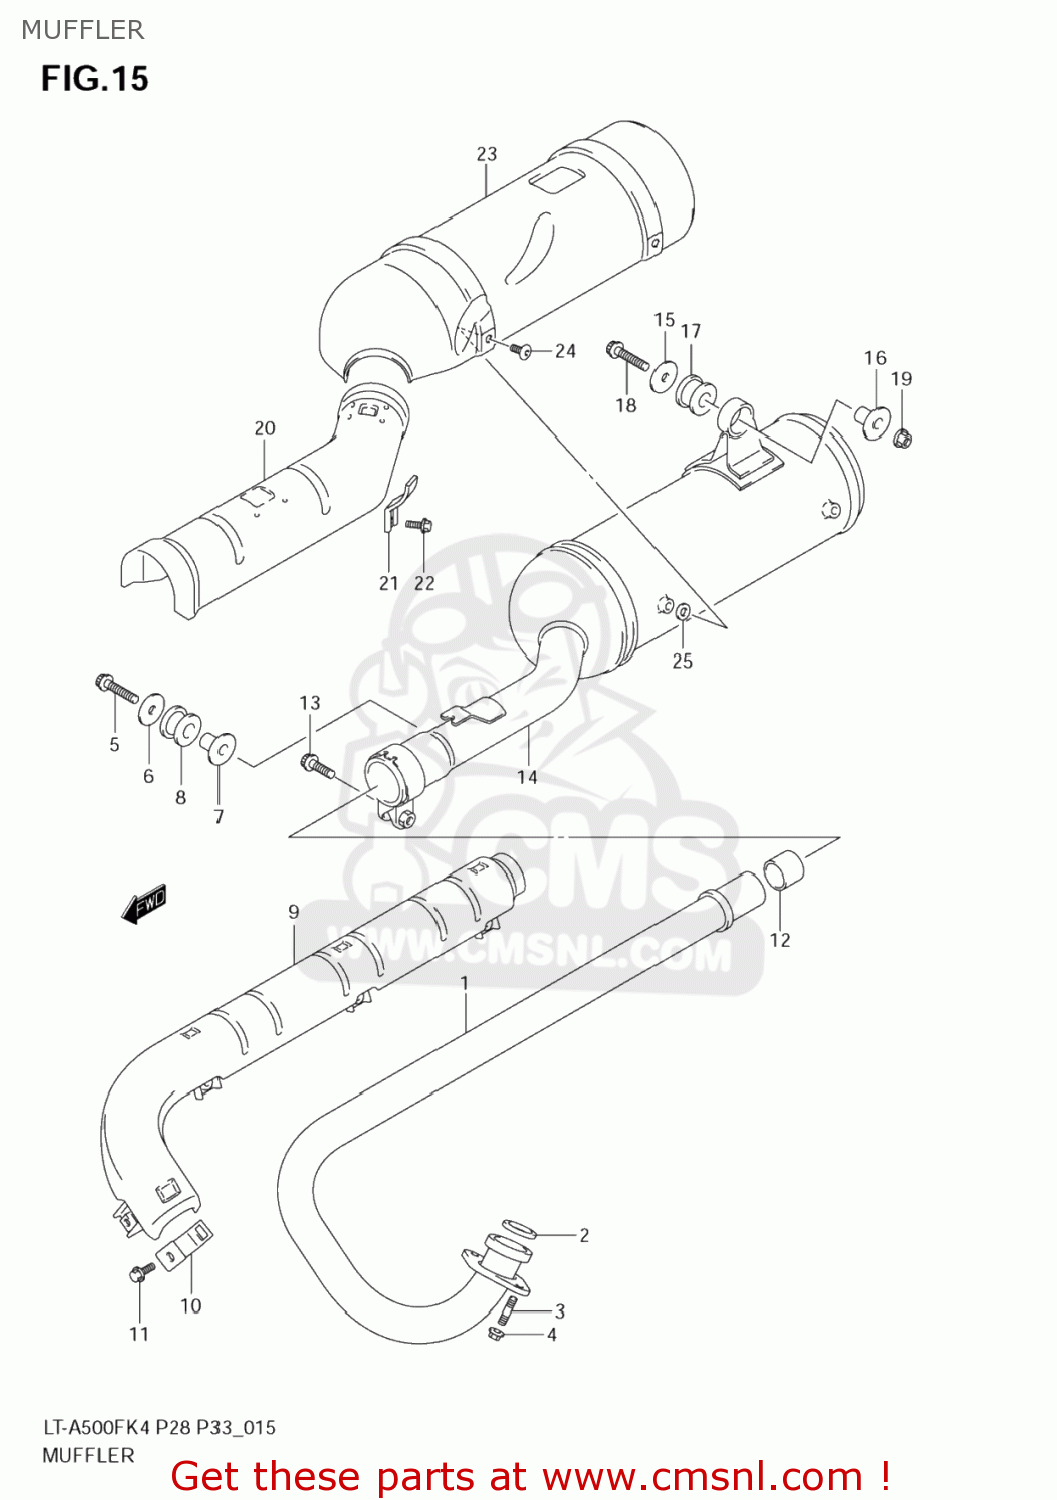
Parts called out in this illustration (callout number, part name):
1	PIPE,EXHAUST
2	GASKET,EXHAUST (NAS)
3	STUD 8X25
4	NUT
5	BOLT(8X35)
6	WASHER(8.5X28X1.6)
7	SPACER(8.6X12X17.5)
8	CUSHION
9	COVER,EXHAUST PIPE
10	CLAMP,EXHAUST PIPE COVER
11	BOLT
12	CONNECTOR,MUFFLER
13	BOLT
14	MUFFLER LT-A500
15	WASHER(8.5X30X2.3)
16	SPACER(8.6X12X24.2)
17	CUSHION
18	BOLT
19	NUT
20	COVER,MUFFLER FR
21	CLAMP,EXHAUST PIPE COVER
22	BOLT
23	COVER,MUFFLER RR
24	SCREW(6X10)
25	GASKET(5.8X13X1.4) (NAS)
